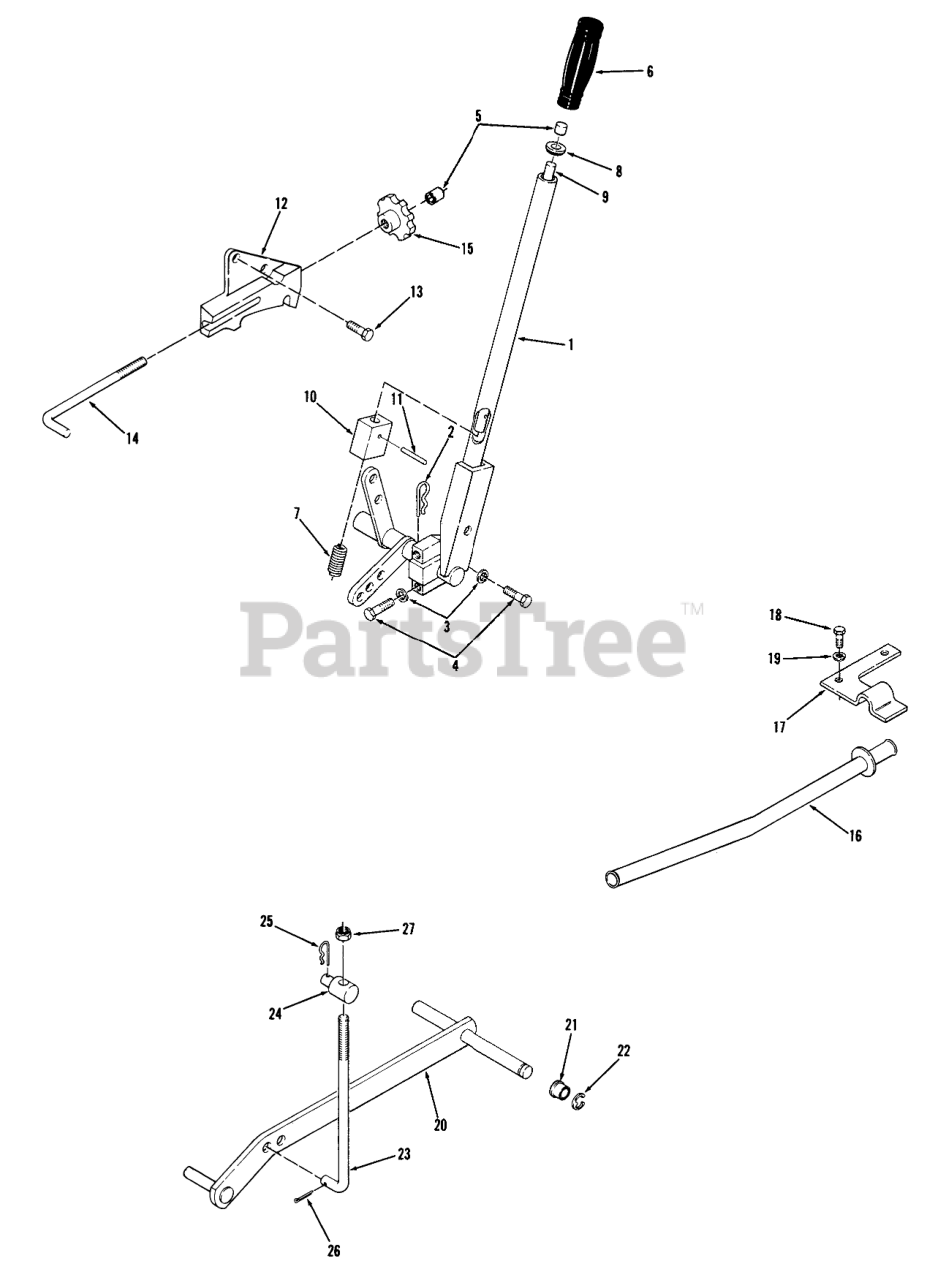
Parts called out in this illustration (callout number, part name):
1	Lift Lever
2	Hairpin
3	Lockwasher
4	H H C S
5	CAP-ROD, PLUNGER
6	HANDGRIP
7	SPRING-COMPRESSION
8	Guide-Rod
9	PLUNGER ROD
10	LOWER PLUNGER R
11	Roll Pin
12	Quadrant
13	Bolt
14	ROD-LIFT CONTROL
15	KNOB-LIFT CONTROL
16	TUBE ASSY COMPLET R
17	Clamp-Tube
18	Bolt
19	LOCKWASHER
20	ASSY LIFT BAR R
21	BUSHING
22	E Ring
23	ROD-LIFT
24	TRUNNION-LIFT
25	Hairpin
26	Cotter Pin
27	NUT
